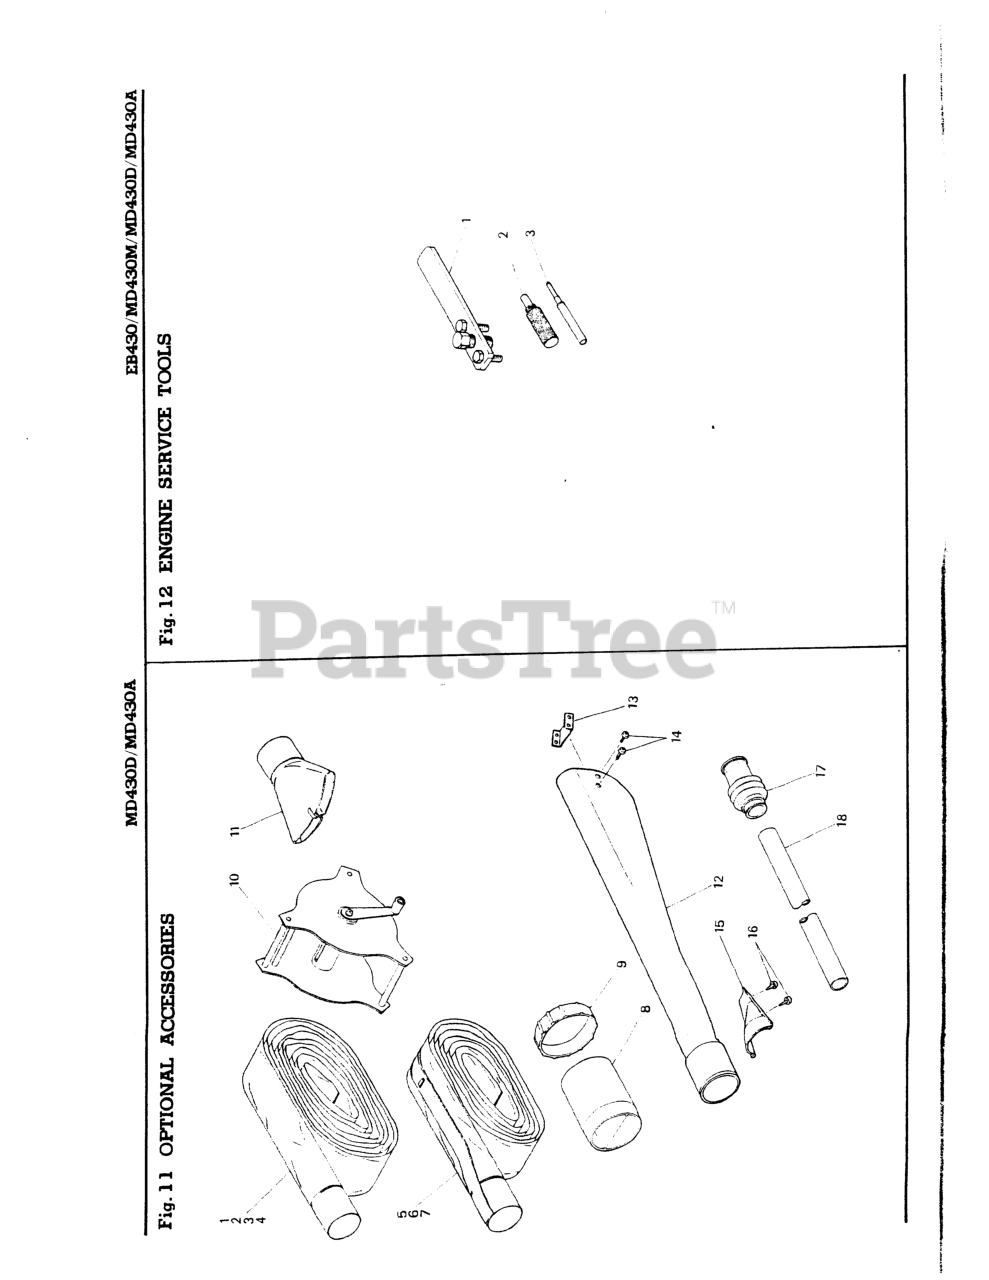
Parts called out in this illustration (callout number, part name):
1	PULLER ASSEMBLY (TOOL)
2	STOPPER (TOOL) (RPLS 3320-9641
3	GUIDE (TOOL)
